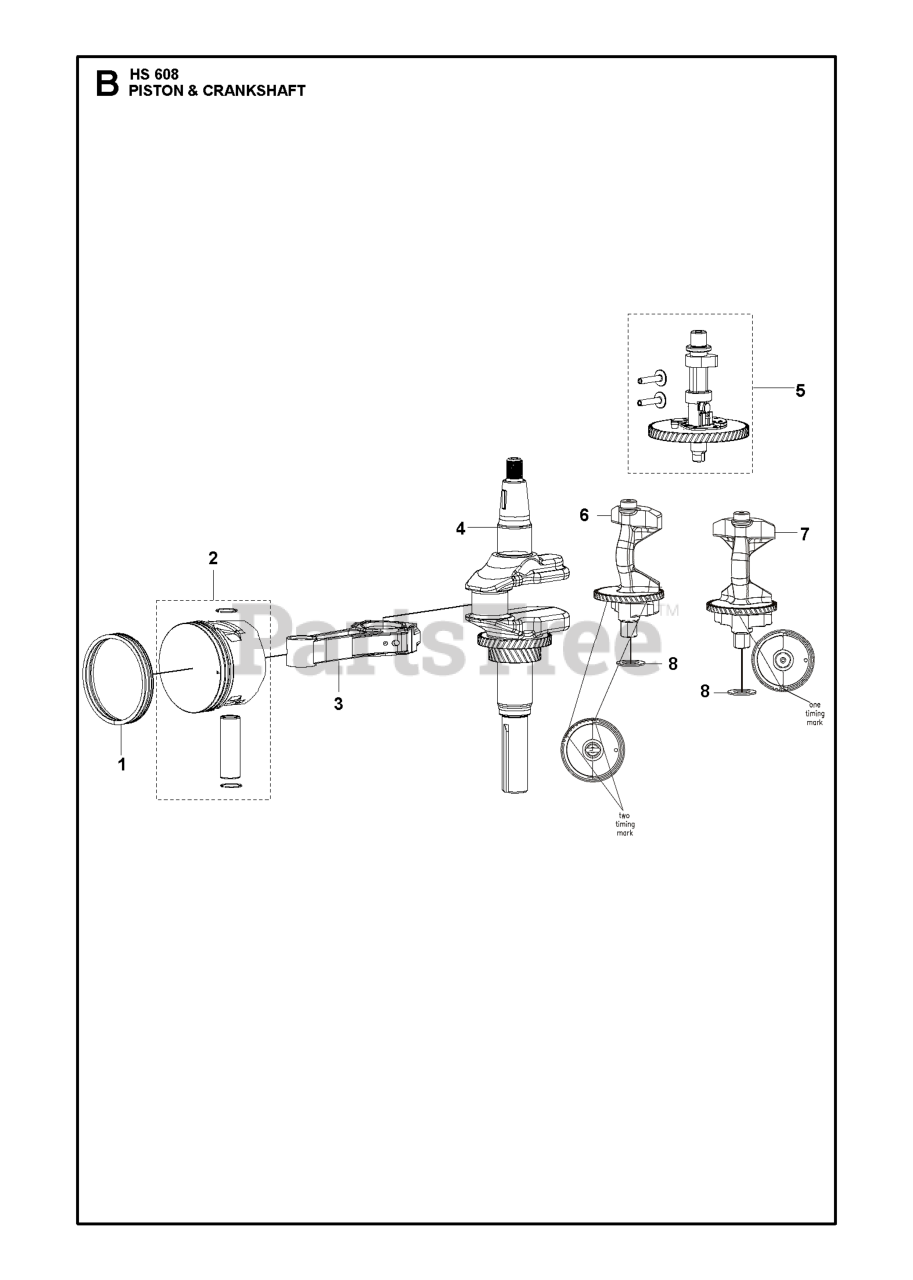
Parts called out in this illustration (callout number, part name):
1	PISTON RING SET
2	PISTON ASSY
3	CONNECTING ROD
4	CRANKSHAFT
5	CAMSHAFT KIT
6	SHAFT BALANCING SHAFT
7	SHAFT BALANCING SHAFT
8	WASHER T430: 20.2 X 34 X 1
